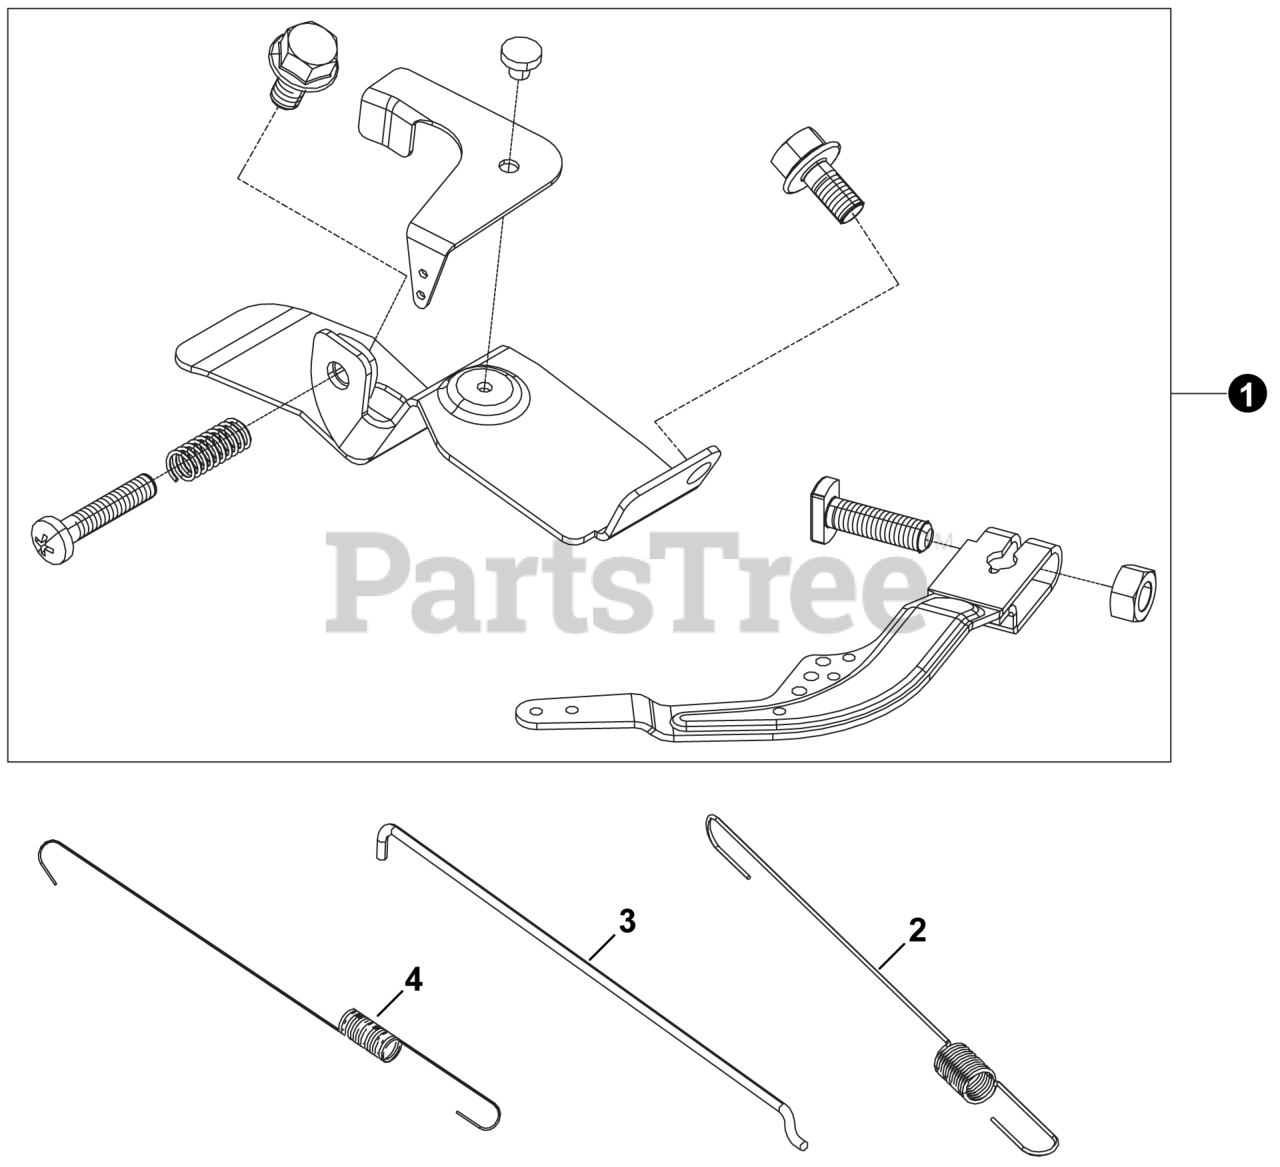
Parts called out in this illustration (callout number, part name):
1	THROTTLE CONTROL ASSY.
2	SPRING, GOVERNOR
3	ROD, GOVERNEOR
4	SPRING, THROTTLE VALVE RETURNING
